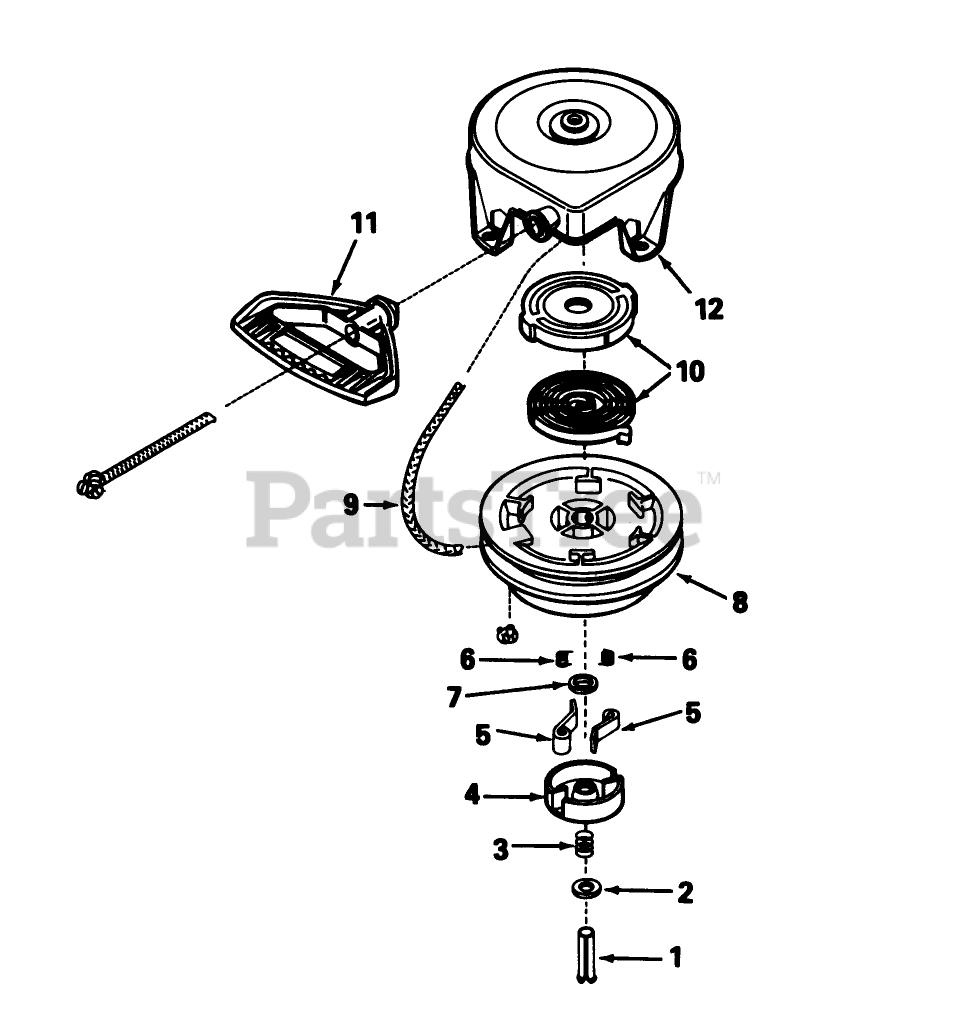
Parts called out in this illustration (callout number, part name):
1	Pin, Spring (Incl. Ref. #7)
2	Washer
3	Brake Spring
4	Retainer
5	Dog-Starter
6	Spring-Dog
7	Washer
8	Pulley
9	Rope-Starter
10	Spring Keeper Assy.
11	Handle-Starter, Mitten Grip
12	Housing Assy., Starter
